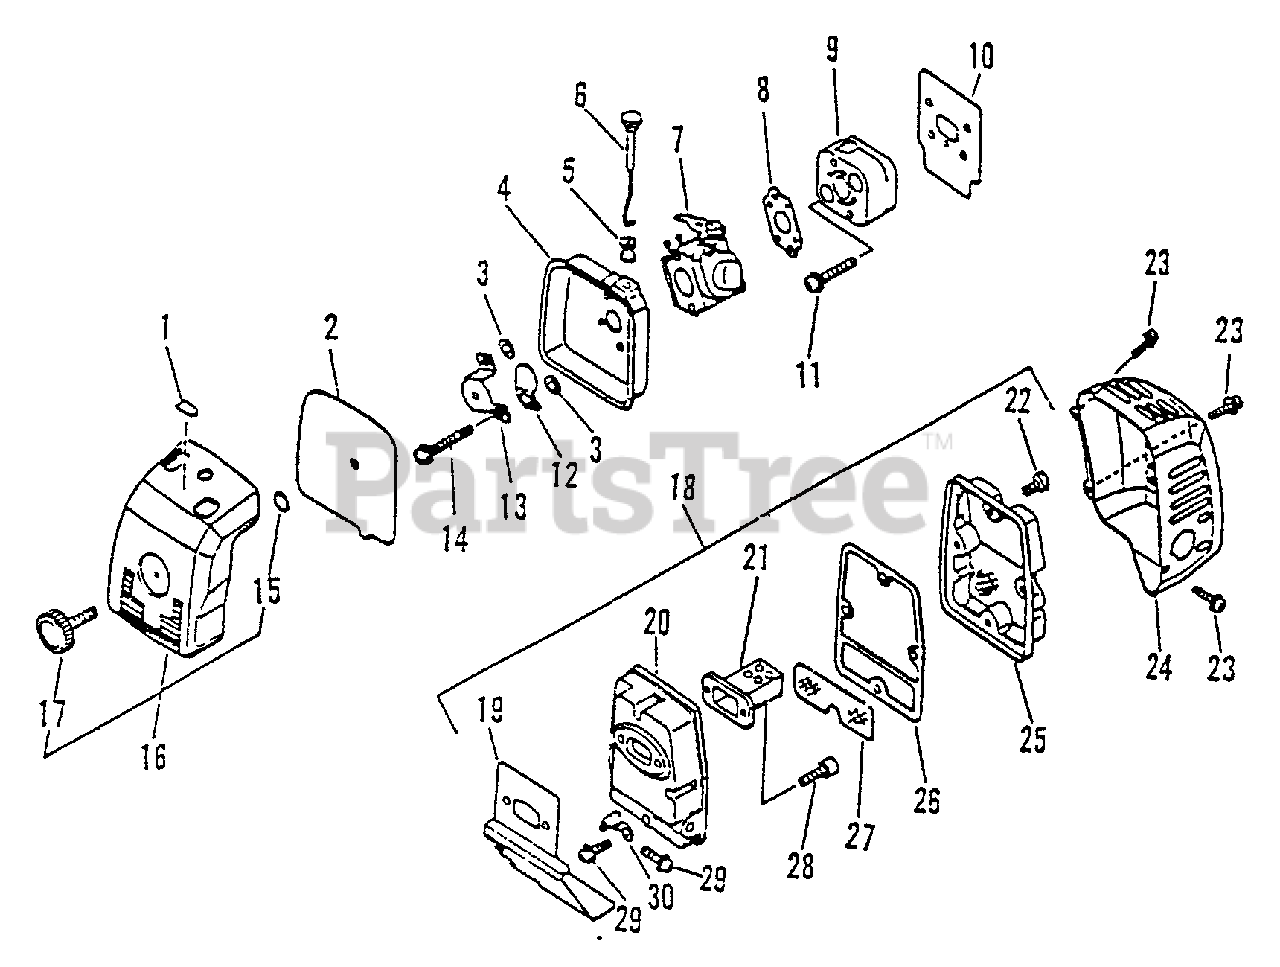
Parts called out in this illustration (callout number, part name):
1	LABEL - CHOKE
2	FILTER, AIR - HEAVY DUTY
3	WASHER - 5
4	CASE, AIR FILTER
6	ROD, CHOKE
7	CARBURETOR C1U-K20
8	GASKET, INTAKE
9	INSULATOR, INTAKE
10	GASKET, INTAKE
11	SCREW - 5X25
12	SHUTTER, CHOKE
13	PLATE, PREVENT
14	SCREW - 5X50
15	O-RING - 3
16	AIR FILTER COVER ASSY
17	THUMBSCREW
18	MUFFLER ASSY
19	GASKET, EXHAUST
21	BAFFLE, MUFFLER
22	SCREW - 5X14
23	SCREW - 4X8
24	COVER, MUFFLER
25	LID, MUFFLER
26	GASKET, EXHAUST
27	SCREEN, SPARK ARRESTOR
28	SCREW - 5X18
29	SCREW - 5X10
30	BRACKET, MUFFLER
